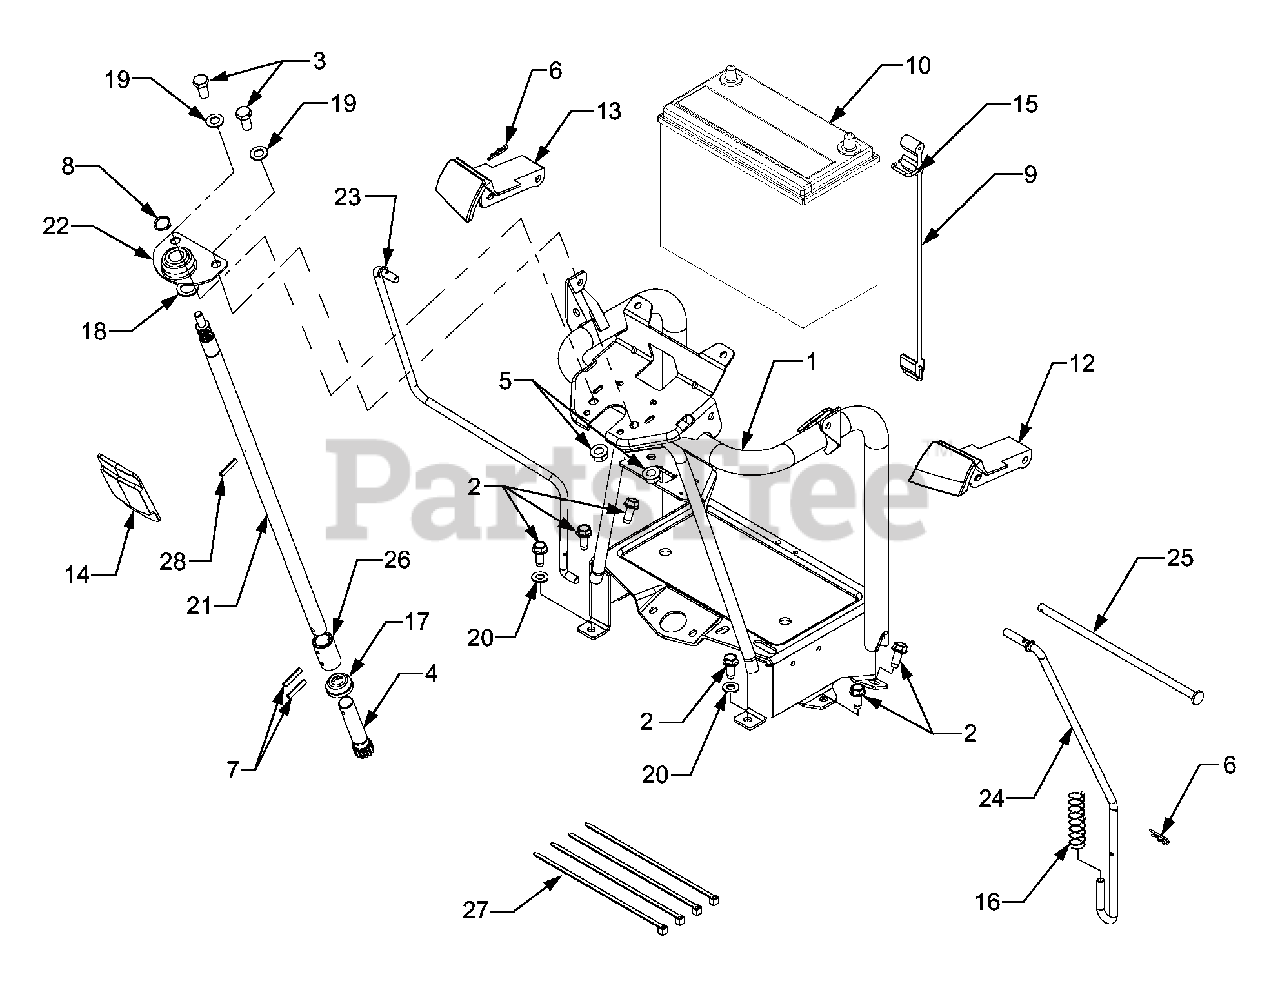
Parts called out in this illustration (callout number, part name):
1	Pedestal Assembly
2	Screw, Hex Wash. Hd. Tapp 5/16-18 x .75
3	Screw, Hex Cap 3/8-16 x .75 GR5
4	Shaft, Lower Steering
5	Nut, Hex Flange Lock, 3/8-16
6	Pin, Internal Cotter
7	Pin, Spirol, 3/16 x 1.0
8	Ring, Retaining, .56 Dia Shaft
9	Strap, Battery
10	Battery
12	Lever, Park Brake
13	Lever, Cruise
14	Cover, Fixed Steering
15	Hook, Wire Rectangular
16	Spring, Compression, .676 x 2.57
17	Boot, Shaft Cover
18	Washer, Flat, .635 x .93 x .06
19	Washer, Flat, .375 x .738 x .063
20	Washer, Flat, .344 x .688 x .065
21	Shaft, Upper Steering
22	Bearing, Steering Support
23	Rod, Cruise Control
24	Rod, Parking Brake
25	Rod, Cruise/Brake Pivot
26	Sleeve, Fixed Steering
27	Cable Tie, Harness
28	Pin, Spirol, 1/8 x .812
